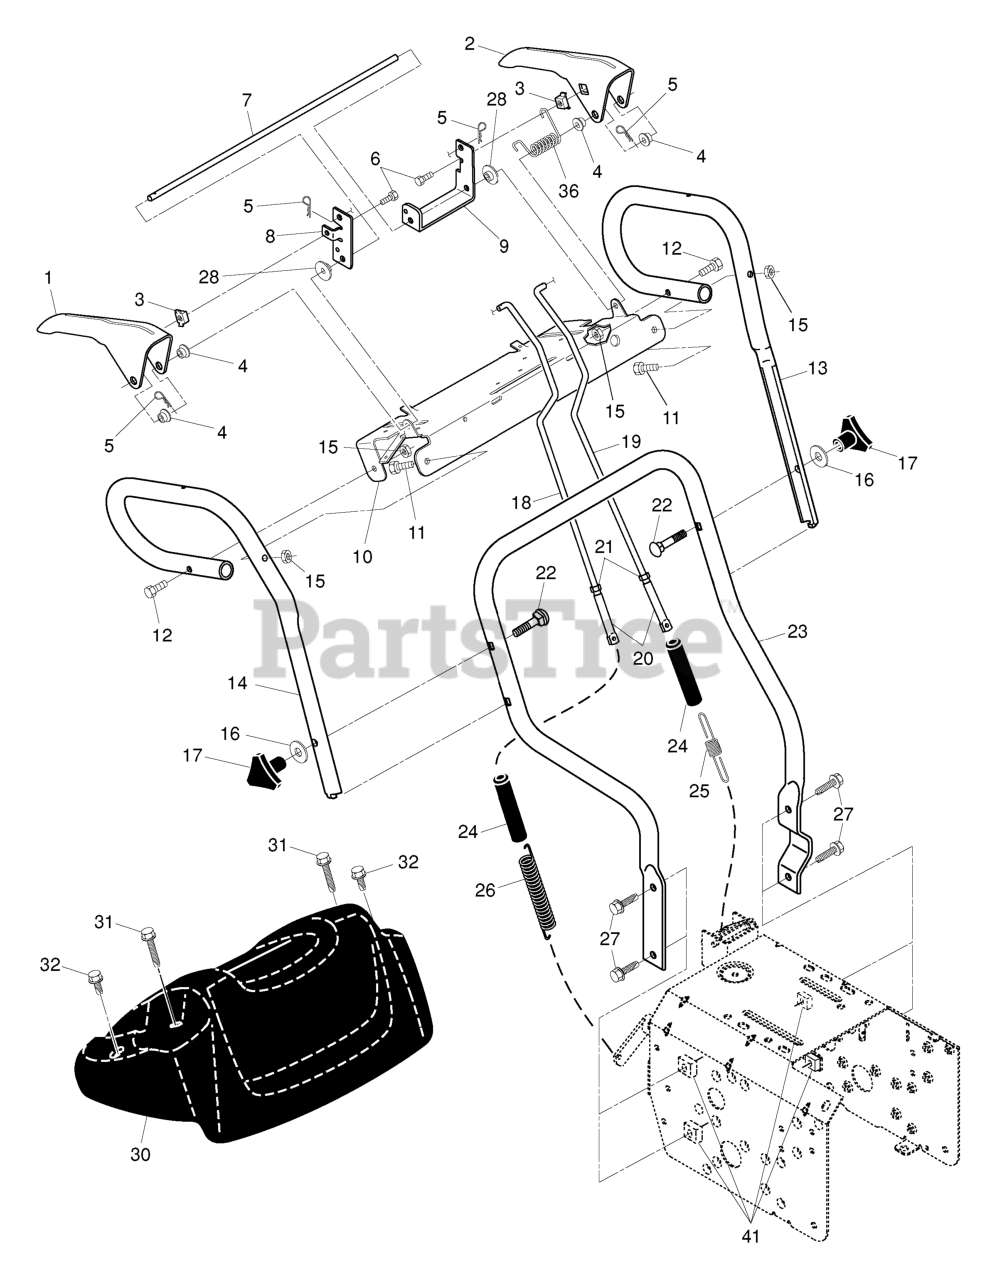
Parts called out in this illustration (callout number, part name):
1	LEVER, AUGER CONTROL
2	LEVER, TRACTION DRIVE CONTROL
3	NUT, CAGE 1/4-20
4	BUSHING, FLANGE
5	SPRING RETAINER
6	SCREW HEX HD 1/4-20 X 3/4
7	ROD.INTERLOCK
8	ARM,IMPELLER ROD
9	ARM,TRACTION ROD
10	PANEL.CONTROL
11	HEX BOLT
13	HANDLE TUBE LH
14	HANDLE TUBE RH
15	NUT.71038.31-18.HEX.NYLOCK
16	WASHER
17	KNOB.HANDLE.3/8.TRI-POINT.BLAC
18	ROD.AUGER.CONTROL
19	ROD.CABLE.TRACTION.LONG
20	ROD, END CONTROL
21	JAM NUT TI
22	BOLT 3/8-16 X 2-1/4
23	TUBE.LOWER.HANDLE.24.BLACK
24	SLEEVE, SPRING
25	SPRING, TRACTION DRIVE
26	SPRING, AUGER CONTROL
27	Screw, Hex Head 3/8-16 x 1
30	CONSOLE, HANDLE
31	SCREW, HEX HD TAPPING #10-24 1
32	SCREW, HEX HEAD, TAPPING
